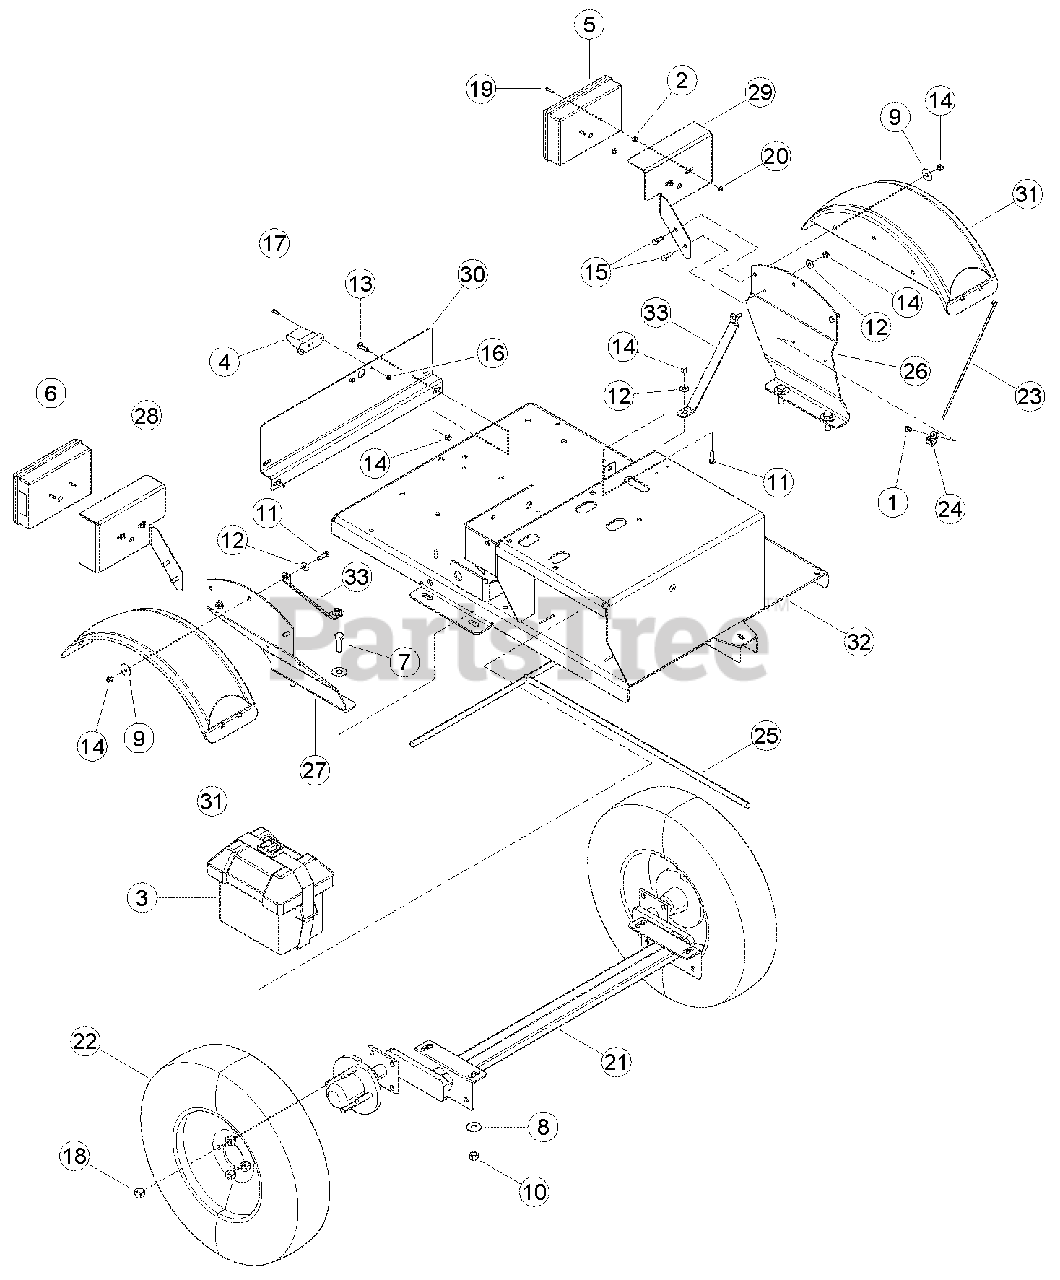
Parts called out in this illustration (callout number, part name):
1	RIVET, 1/4 X 3/4 ST POP
2	GROMMET, 1/4 X 5/8 RUBBER
3	BOX, SMALL BATTERY
4	LIGHT, LICENSE PLATE
5	LIGHT, TAIL RH
6	LIGHT, TAIL LH
7	BOLT, 1/2 X 1-1/2 HEX HD GR5 ZP
8	WASHER, 1/2 FLAT ZP
9	WASHER, 5/16 FENDER ZP
10	NUT, 1/2 CENTERLOCK GRB ZP
11	BOLT, 5/16 X 1 HEX HD GR5 NC ZP
12	WASHER, 5/16 FLAT ZP
13	BOLT, 5/16 X 1 CRG GR5 ZP
14	NUT, 5/16 NE NYLOCK ZP
15	BOLT, 5/16 X 7/8 HEX HD GR5 NC ZP
16	NUT, 10/24 NYLOCK TYPE NM, ZP
17	MACH. SCREW, #10-24 X 3/4 PAN HD PH ZP
18	NUT, 1/2-20 WHEEL
19	BOLT, 10-24 X 3/4 HEX HD GR8 PLAIN
20	NUT, #10-24 K-LOCK ZP
21	AXLE, 1000LB TORSION
22	ASSEMBLY, 5.30-12 TIRE + SPOKE RIM
23	STRAP, 11 IN BLACK TIE
24	CLAMP, CABLE MOUNT
25	HARNESS, C/S TRAILER
26	BRACKET, LH FENDER
27	BRACKET, RH FENDER
28	BRACKET, LIGHT
29	BRACKET, LIGHT
30	PLATE, MOUNTING
31	FENDER, BLACK PLASTIC DRILLED
32	WELDMENT, C/S TRAILER
33	BRACE, FENDER
